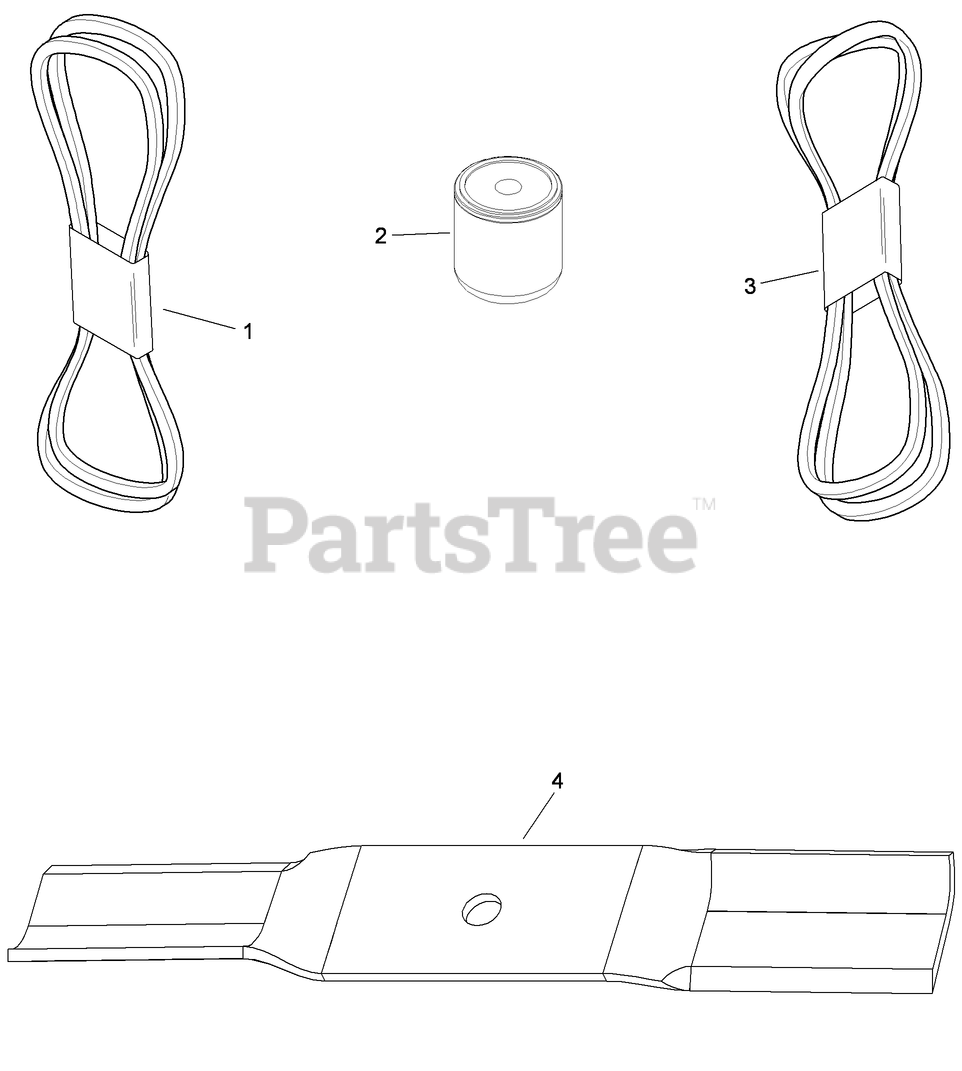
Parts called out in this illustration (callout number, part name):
1	BELT-PUMP
2	FILTER-OIL, HYD
3	V-BELT, DRIVE
